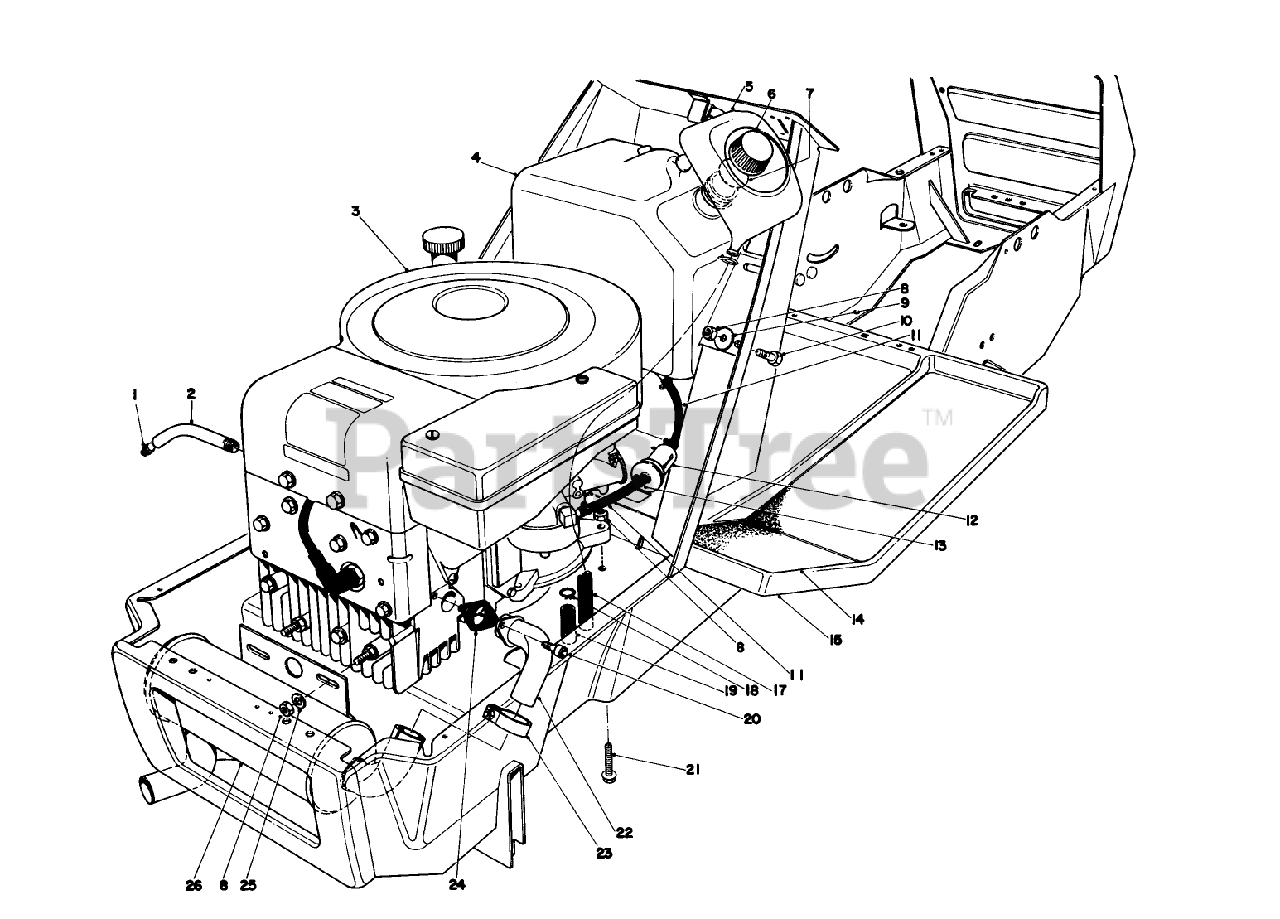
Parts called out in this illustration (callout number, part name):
1	PLUG-PIPE, SQH
3	Engine
5	Funnel-Overflow
8	NUT-LOCK, CONE
10	SCREW-HH
13	CLAMP-HOSE
17	FUNNEL HOSE
20	SCREW-HSH
21	SCREW-HH
24	Exhaust Gasket
25	WASHER-PLAIN
